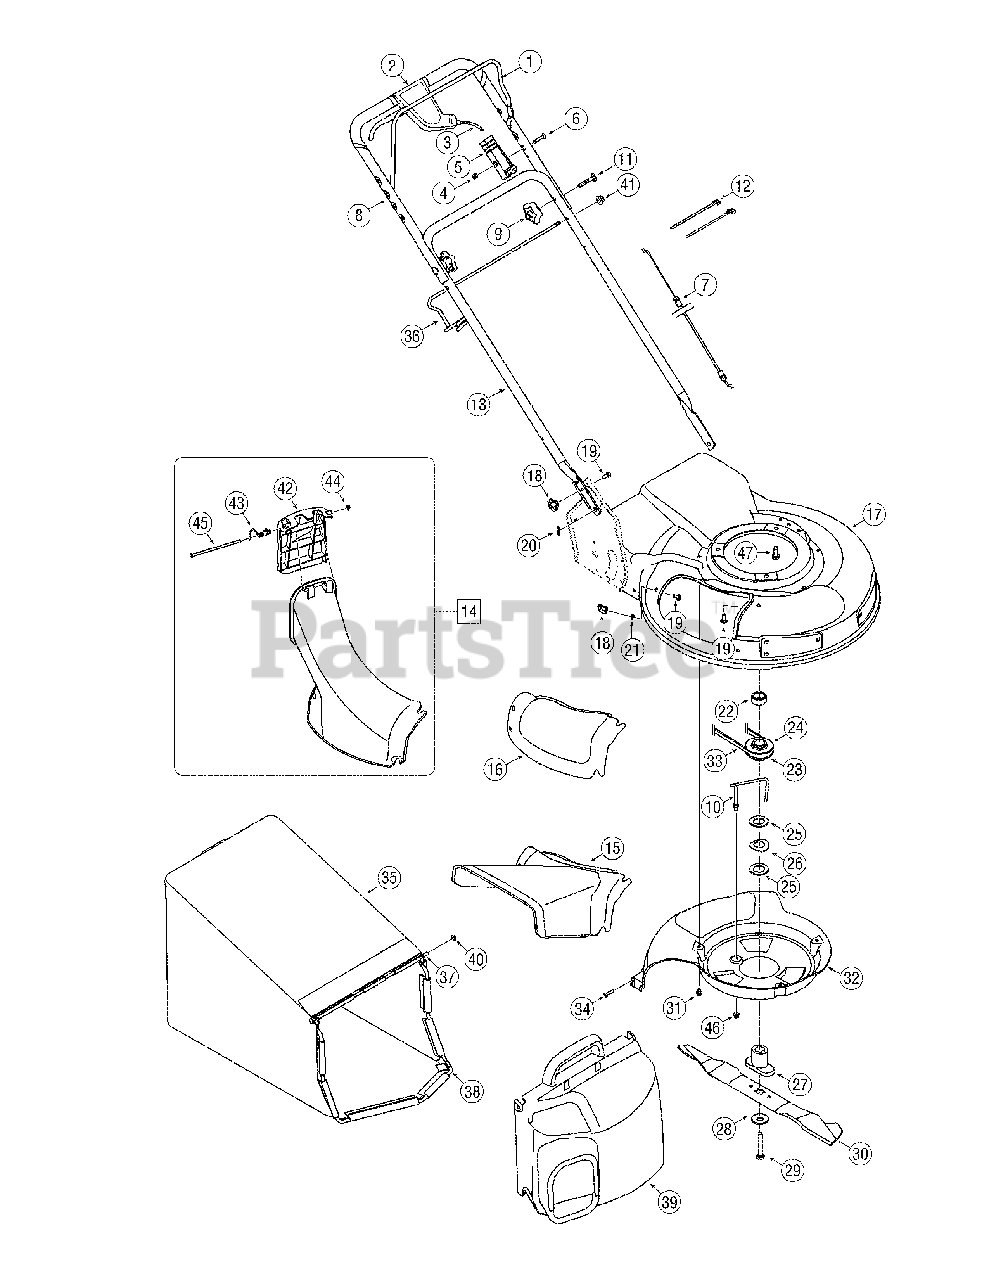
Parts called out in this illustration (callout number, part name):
1	Control Lever
2	Control Lever Assembly
3	Drive Cable 51"
4	Top Lock Nut 1/4-20
5	Control Housing
6	Oval C-Sunk Screw
7	Control Cable 47"
8	Upper Handle
9	Star Knob
10	Belt Keeper
11	Carriage Bolt 5/16-18 x 2.0
12	Cable Tie
14	Chute Assembly
15	Side-Discharge Chute
16	Mulch Cover
19	Carriage Bolt 1/4-20 x .75"
20	Cotter Pin
21	Push Nut .25 x ID x .50 OD
22	Slv. Spcr., 25mm x 1.375 x .440
23	Half Pulley: Key 25mm x 2.62 OD
24	Half Pulley: Upper 25mm x 2.62
25	Flat Washer 1.031 x 1.620 x .095
26	Wave Washer, 1.5 x 1.0 x .029
27	Blade Adapter
28	Bell Washer, .396 x 1.140 x .095
29	Hex Bolt 3/8-24 x 2.5
30	21" Mulching Blade
31	Screw 1/4-20 x 3.75
33	Belt 3/8 x 39.24
34	HL Screw 1/4-15 x .75
35	Grass Catcher
36	Support Rod w/ Rope Guide
37	Pivot Rod
38	Grass Bag Frame
39	Grass Bag Cover
40	Cap Nut
41	Hex Nut 5/16-18
42	Chute Door
43	Torsion Spring
44	Push Cap
45	Pivot Rod
46	Flange Lock Nut, 14-20
47	Sems Screw 3/8-16 x 1.00
